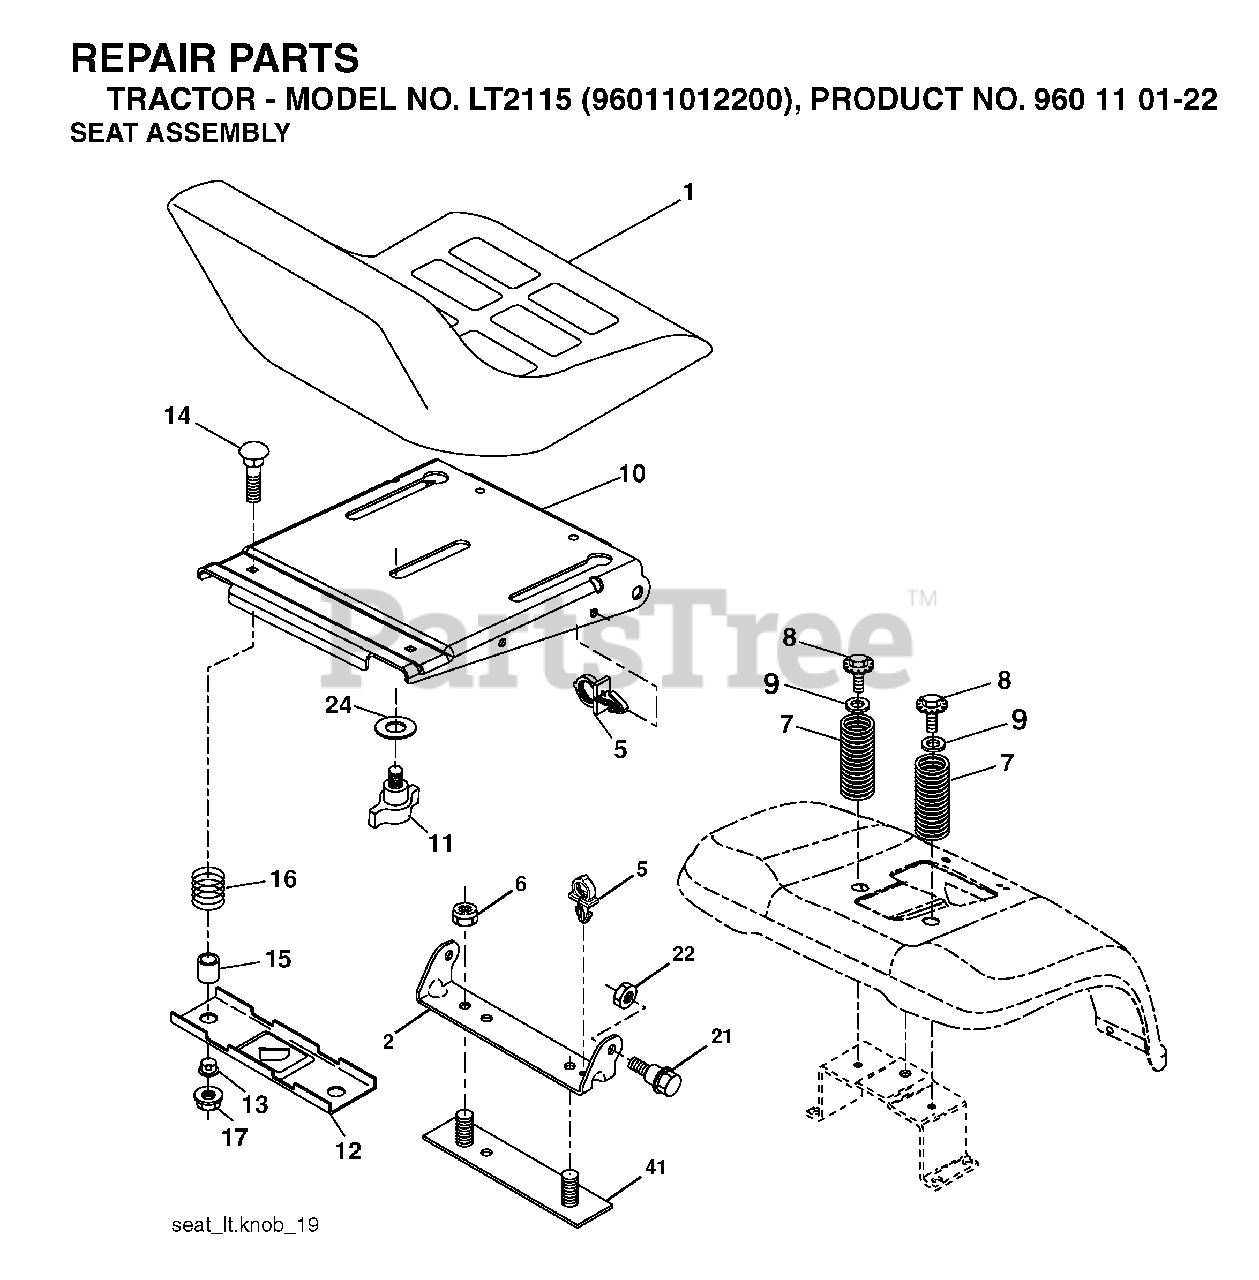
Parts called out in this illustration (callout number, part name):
2	BRKT.PIVOT.FENDER
5	PUSH CLIP
6	NUT
7	SPRING COMPRESSION
8	SCREW 3/8-16X1
9	WASHER
11	KNOB.SEAT.ADJ.WINGNUT
12	BRKT.MNTNG.SWITCH.SEAT
14	BOLT.ROUND.HEAD.SQUARE.NECK
15	SPACER SPLIT 28X.96
17	NUT T
21	BOLT.SHOULDER.5/16-18
22	NUT.71038.31-18.HEX.NYLOCK
